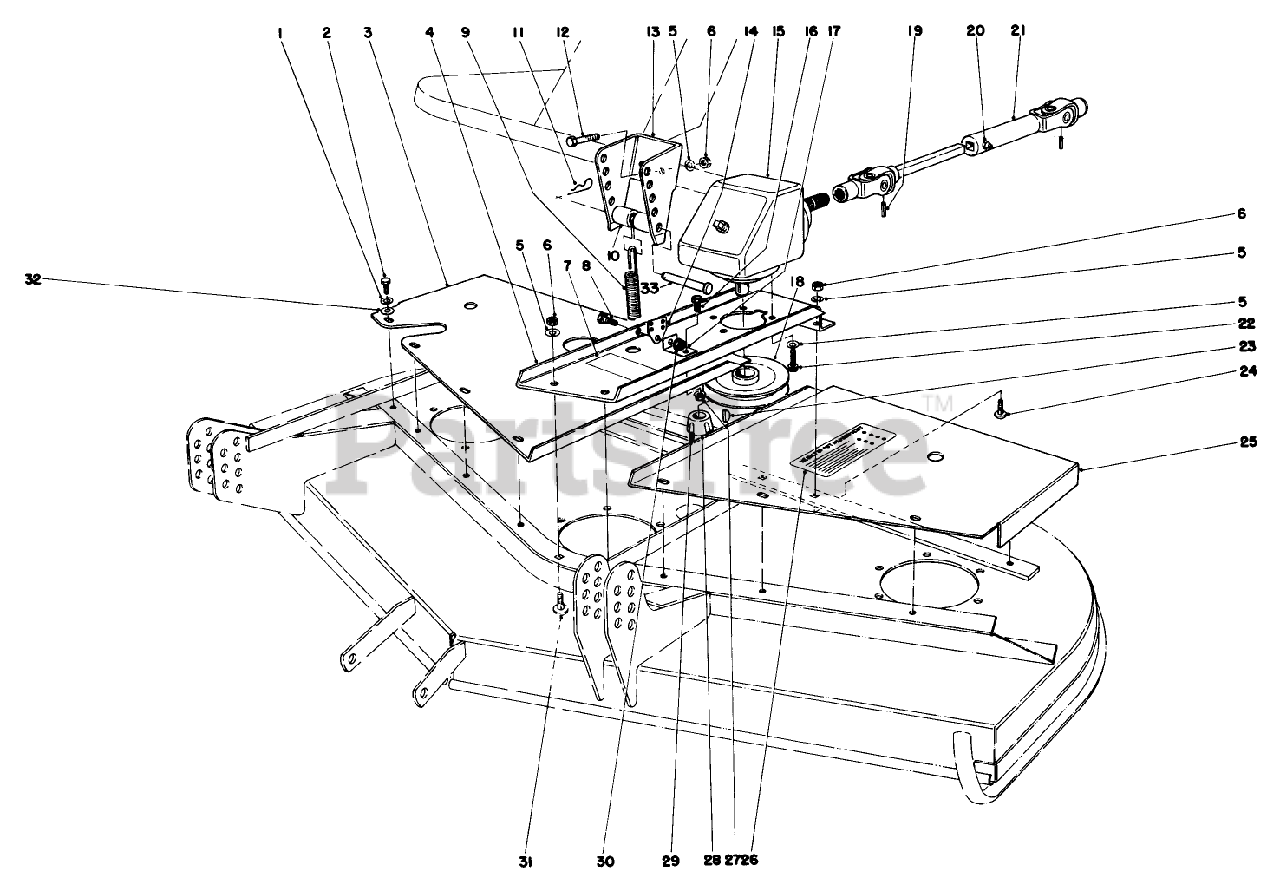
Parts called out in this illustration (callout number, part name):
1	SCREW-HH
2	SCREW THD 1/4 20 5/8
3	RH COVER WA *R
5	WASHER-LOCK
6	NUT-HEX
8	BOLT-SHOULDER
10	SPACER
11	PIN-HAIR
12	SCREW-HH
13	SPRING BRACKET *R
16	SCREW-HH
17	EXTENSION BRKT *R
19	PIN-ROLL
20	FITTING-GREASE
21	UNIVERSAL JOINT
22	SCREW-HSH
23	KEY-WOODRUFF
24	SCREW-HH
25	LH COVER WA *R
27	NUT-HF
28	BUSHING-LOCK, TAPER
29	SCREW-SET, HSH
30	NUT-HHF, WHIZ
31	SCREW-CARR
32	WASHER-FLAT
33	PIN-CLEVIS
